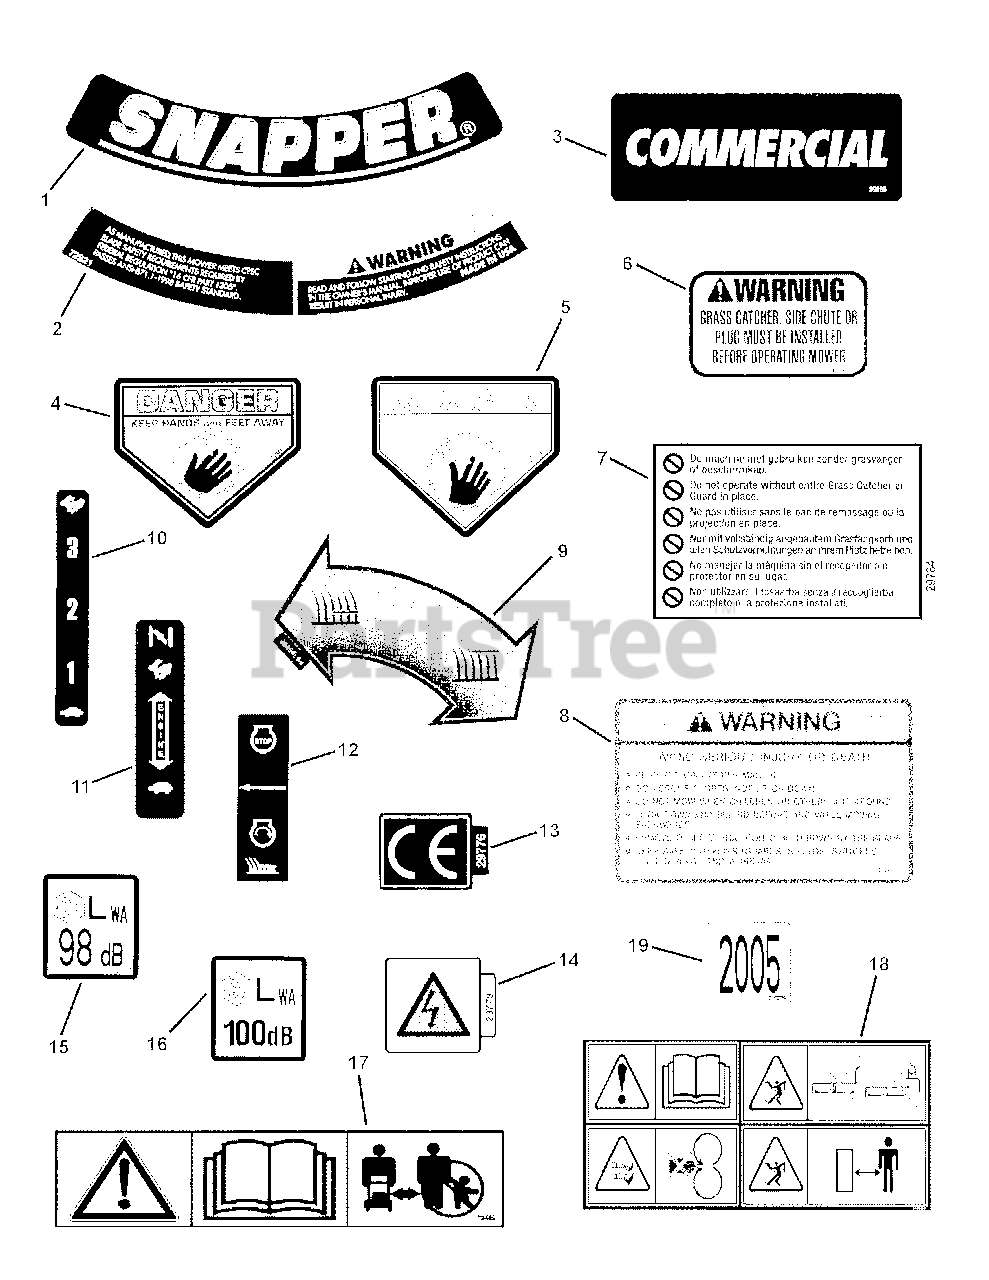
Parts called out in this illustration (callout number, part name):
1	DECAL, SNAPPER
2	DECAL, Warning (Deck)
3	DECAL, Commercial, Walk-Behind Mower
4	DECAL, Danger (Keep Hands and Feet Away)
5	DECAL, Warning (International Symbol)
6	DECAL, Chute Deflector (Cast)
7	DECAL, Chute/International Warning
8	DECAL, Warning 1997
9	DECAL, Height Control Instruction (Euro)
10	DECAL, Speed Shift- ELP, ECLP
11	DECAL, Throttle Control, KWV
12	DECAL, OPC Bail International Symbol
13	DECAL, European Community (CE)
14	DECAL, Spark Plug International Symbol
15	DECAL, Noise, 98 dB
16	DECAL, Noise, 100 dB
17	DECAL, Caution Symbols
18	DECAL, Warning, Euro Multi-Panel
19	DECAL, 2005 Year of Manufacture
